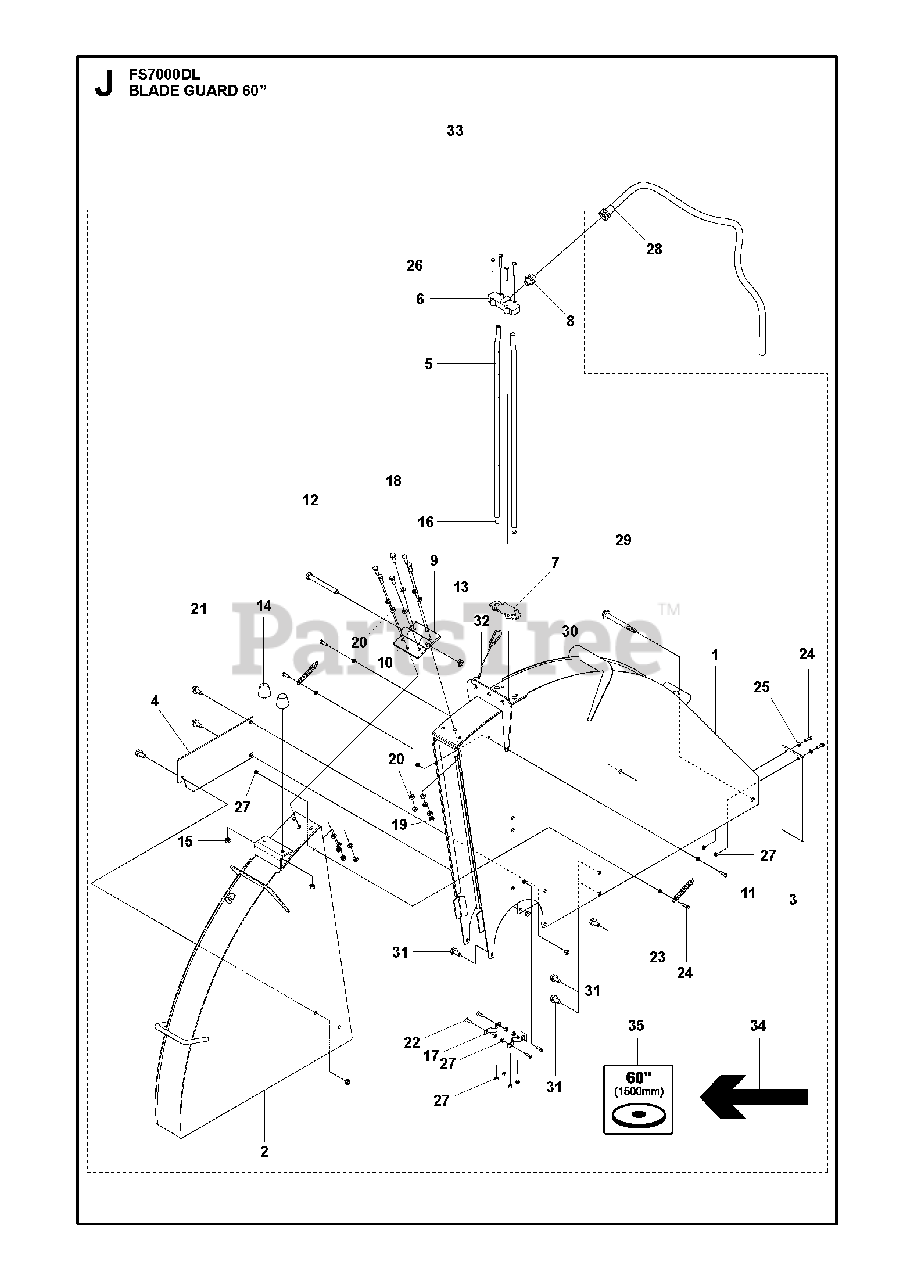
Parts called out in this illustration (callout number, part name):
19	HEXAGON LOCKING NUT
20	WASHER
27	HEXAGON LOCKING NUT
33	BLADE GUARDIncluding decals
